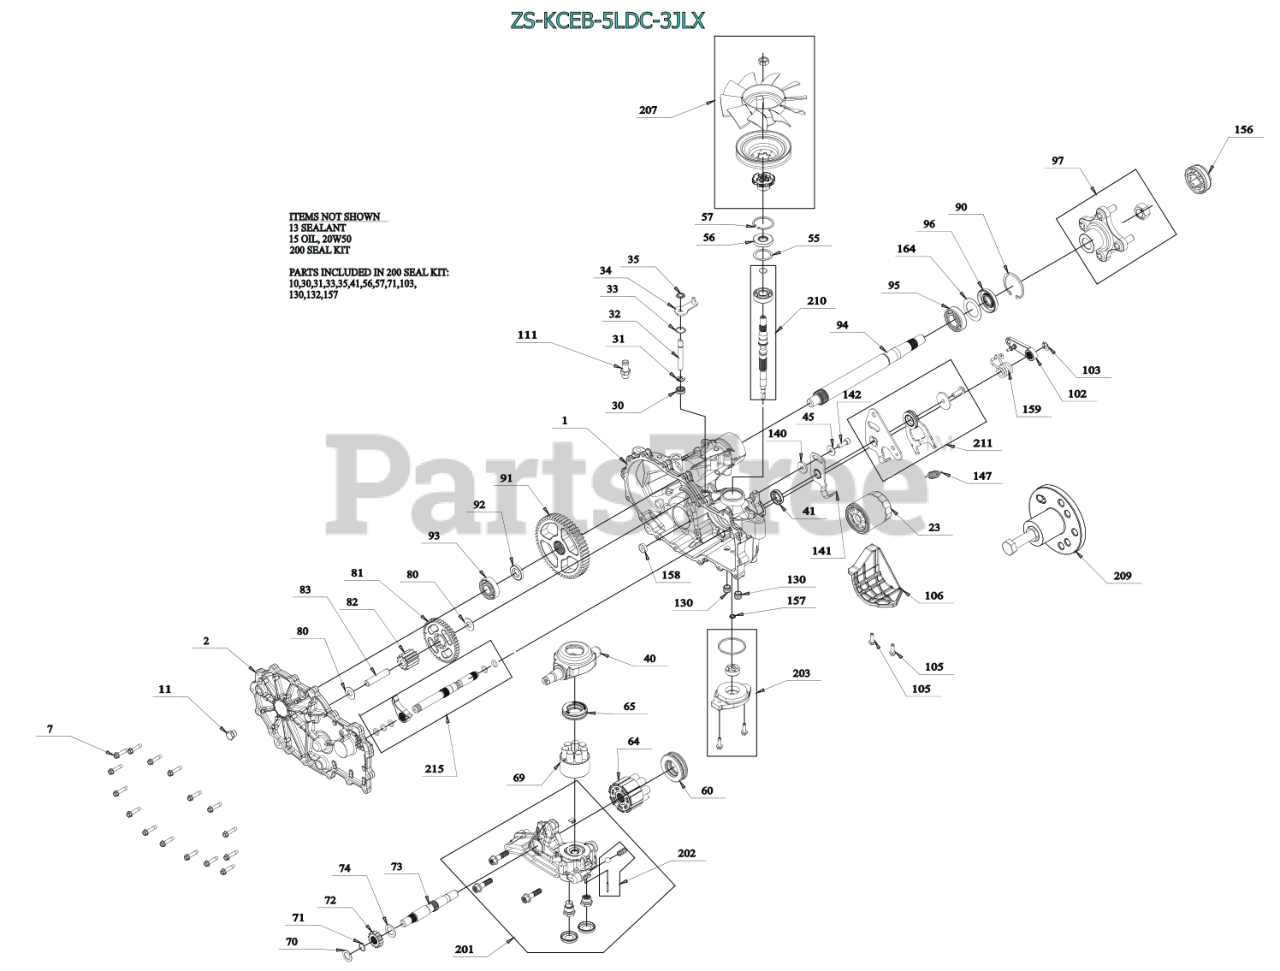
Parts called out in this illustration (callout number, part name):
1	KIT, MAIN HOUSING LH, CHARGE, CONTROL
2	KIT, COVER, SIDE LH
7	SCREW,HEX WASHER 1/4-20X1.125
23	OIL FILTER, TRANSMISSION
30	SEAL, LIP .375X.75X.25
31	RING. RETAINING
33	RING, RET .750
34	HG BYPASS ARM (52370)
35	RING, RTNG .
40	TRUNNION, SWASHPLATE
41	SEAL, LIP 18X32X7
45	WASHER
55	WASHER 1.23X1.56X.04
56	SEAL, LIP 17X40X7
57	RING, RET 1.56 INT
60	HG THRUST BEARING (51462)
64	HG 16CC CYLINDER BLOCK (71579)
65	HG THRUST BLOCK (53502)
69	HG SEVEN PISTON BLOCK (71971)
70	WASHER .63X1.0X.05
71	RING, RET 62 EXT
72	GEAR, 14T (STEEL)
73	SHAFT, MOTOR
74	WASHER .71 X 1.16 X .04
80	WASHER .5X1.0X.032
82	GEAR, 11T (STEEL)
83	JACK SHAFT (PIN)
90	RING, RETAINING
91	GEAR, 54T
93	KIT, BEARING
94	GEAR, 54T
95	BEARING, BALL 25.4 X 52 X 15
96	SEAL, LIP
97	KIT, HUB 4 BOLT
102	HG ACTUATING KIT HANDLE
103	CLIP,BRAKE ARM HYDROGEAR 52027
105	HFHCS 1/4-20X.75
106	HG FILTER GUARD LH (52247)
111	KIT, FITTING 1/2 BEADED 9/16
130	TUBE, CHARGE TRIPLE O - RING
141	ARM, NEUTRAL LEFT
142	SHCS 5/16-24X1 PATCH
147	SPRING, HYDROGEAR P/N 51833
156	CAP, AXLE
157	KIT, GEROTOR SEAL
158	MAGNET, RING
159	SPRING, TORSION, CW
164	WASHER, 1.355 X 2.035 X .021 FLAT
200	HG SEAL KIT (71976)
201	KIT, CENTER SECTION, LH CHARGE
202	KIT, CHARGE RELIEF
203	KIT, CHARGE PUMP
207	KIT, FAN/PULLEY
209	HUB PULLER 5 BLT
210	INPUT SHAFT HG 71978
211	KIT, RTN BIDIRECTIONAL
215	KIT, OUTBOARD, RH ROT B / LH ROT A
